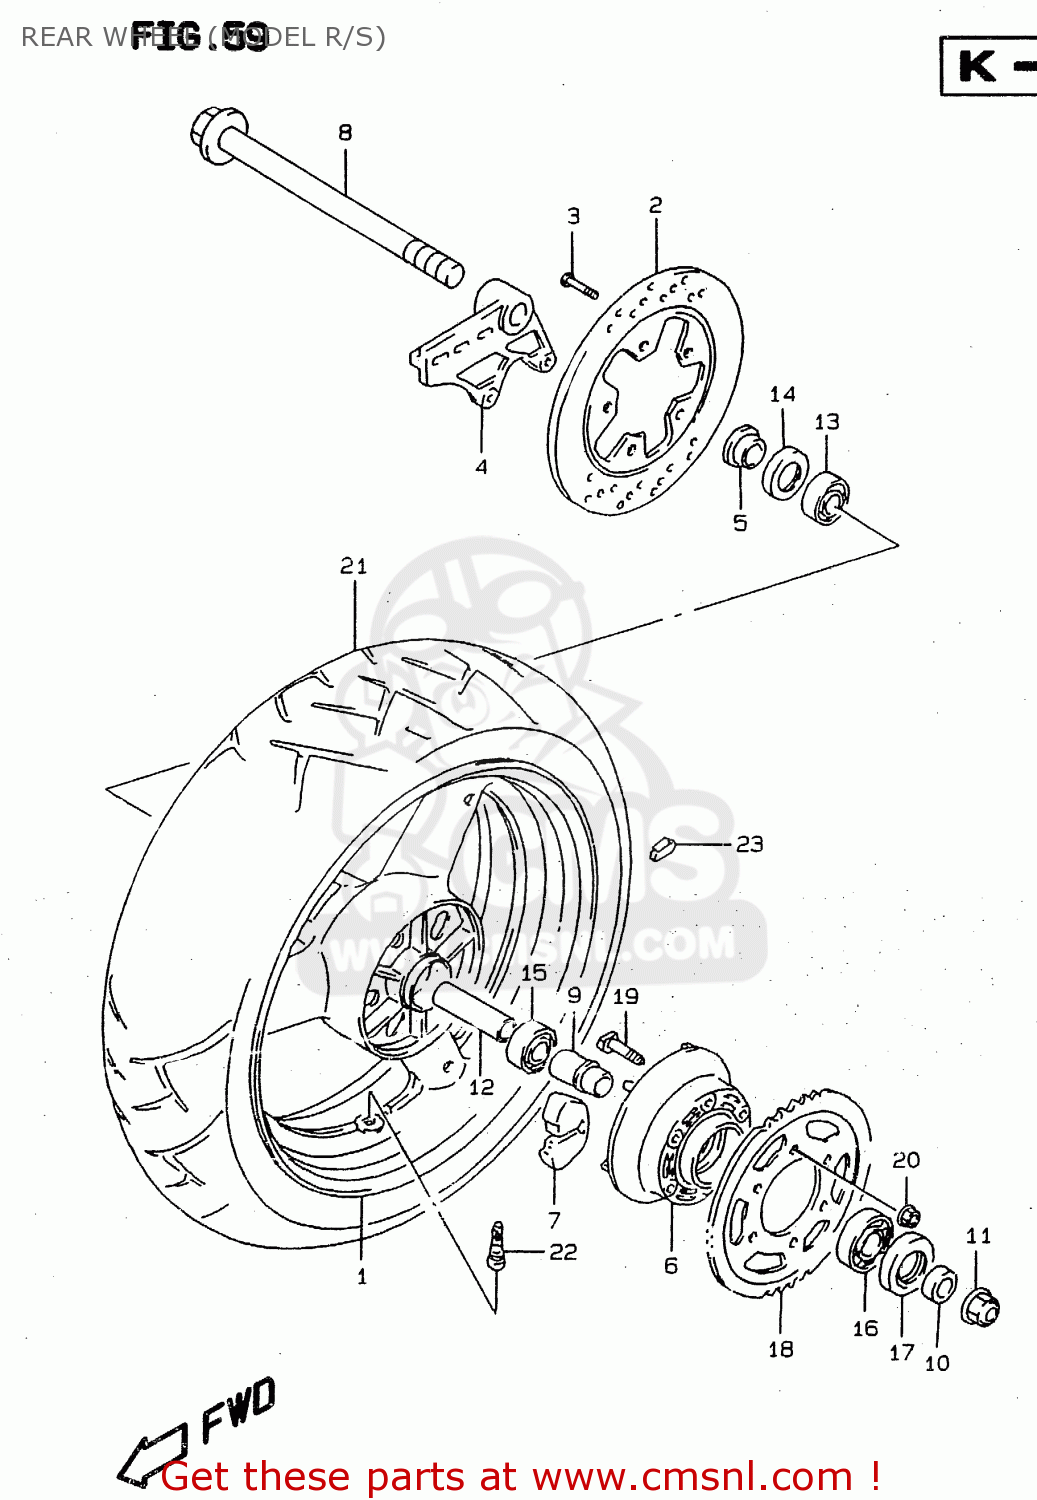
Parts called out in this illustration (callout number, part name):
1	WHEEL,REAR
2	DISC,RR BRAKE
3	BOLT 8X33
4	BRACKET,REAR CALIPER
5	SPACER,RR AXLE,R
6	DRUM,RR SPROCKET
7	ABSORBER,RR HUB SHOCK
8	AXLE,RR
9	RETAINER,RR HUB BEARING
10	SPACER,RR AXLE,L
11	NUT
12	SPACER,RR WHEEL HUB BEARING
13	BEARING(20X47X14)
14	SEAL,OIL(28X47X7)
15	BEARING(20X47X14)
16	BEARING(25X62X17)
17	SEAL,OIL(35X62X8)
18	SPROCKET, REAR (NT:43)
19	BOLT
20	NUT
21	TIRE,REAR 170/60 ZR17
22	VALVE ASSEMBLY,WHEEL,TR412
23	BALANCER,WHEEL (10G)
